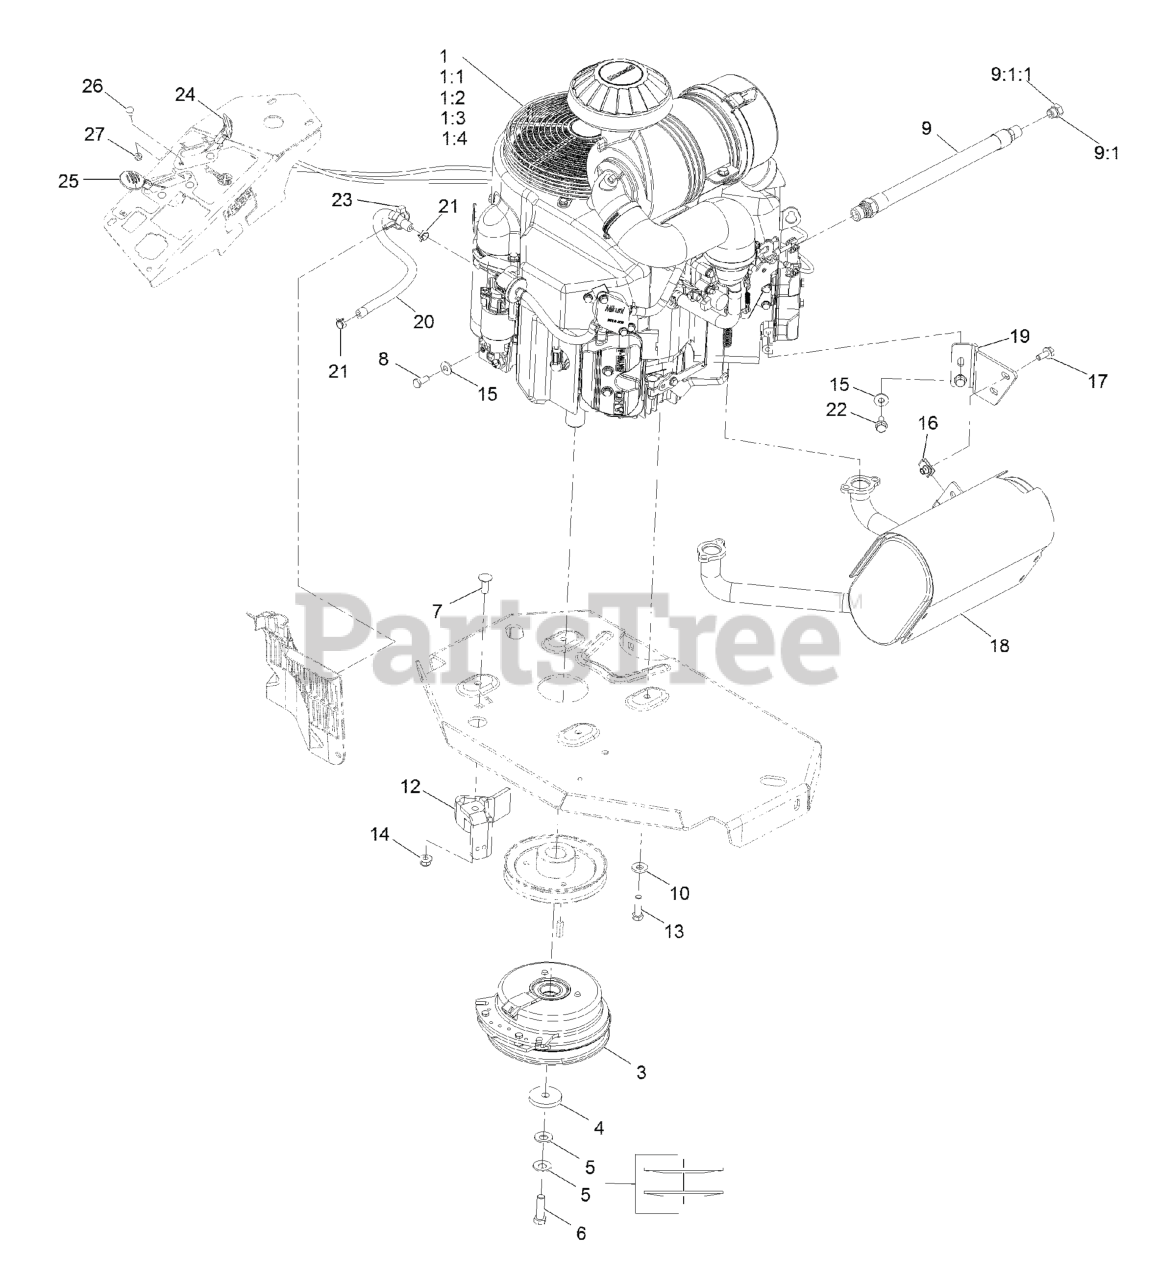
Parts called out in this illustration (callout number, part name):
1:1	Kawasaki 49065-2078 Engine Oil Filter
1:2	Kawasaki 49019-7001 Fuel Filter
1:3	Kawasaki 11013-7039 Safety Filter
1:4	Kawasaki 11013-7038 Air Filter
3	CLUTCH KIT
4	WASHER-CLUTCH
5	WASHER-SPRING
6	SCREW-HH 7/16-20 X 1 1/2 W/LOCTITE
7	SCREW-CARR
8	SCREW-HH
9	ENGINE OIL DRAIN HOSE ASM
9:1	PLUG-HH
9:1:1	O-RING
10	WASHER-BELLEVILLE
12	CLUTCH-ANCHOR
13	SCREW-HH
14	NUT-HF, NI
15	WASHER-SPRING
17	SCREW-HHF
18	MUFFLER
19	BRACKET-MUFFLER
20	HOSE-FUEL
21	CLAMP-HOSE
22	SCREW-HHF
23	CLAMP-HOSE
24	ASM, CHOKE CABLE
25	ASM,THROTTLE CABLE
26	BOLT-CARR
27	NUT-LOCK, NI
